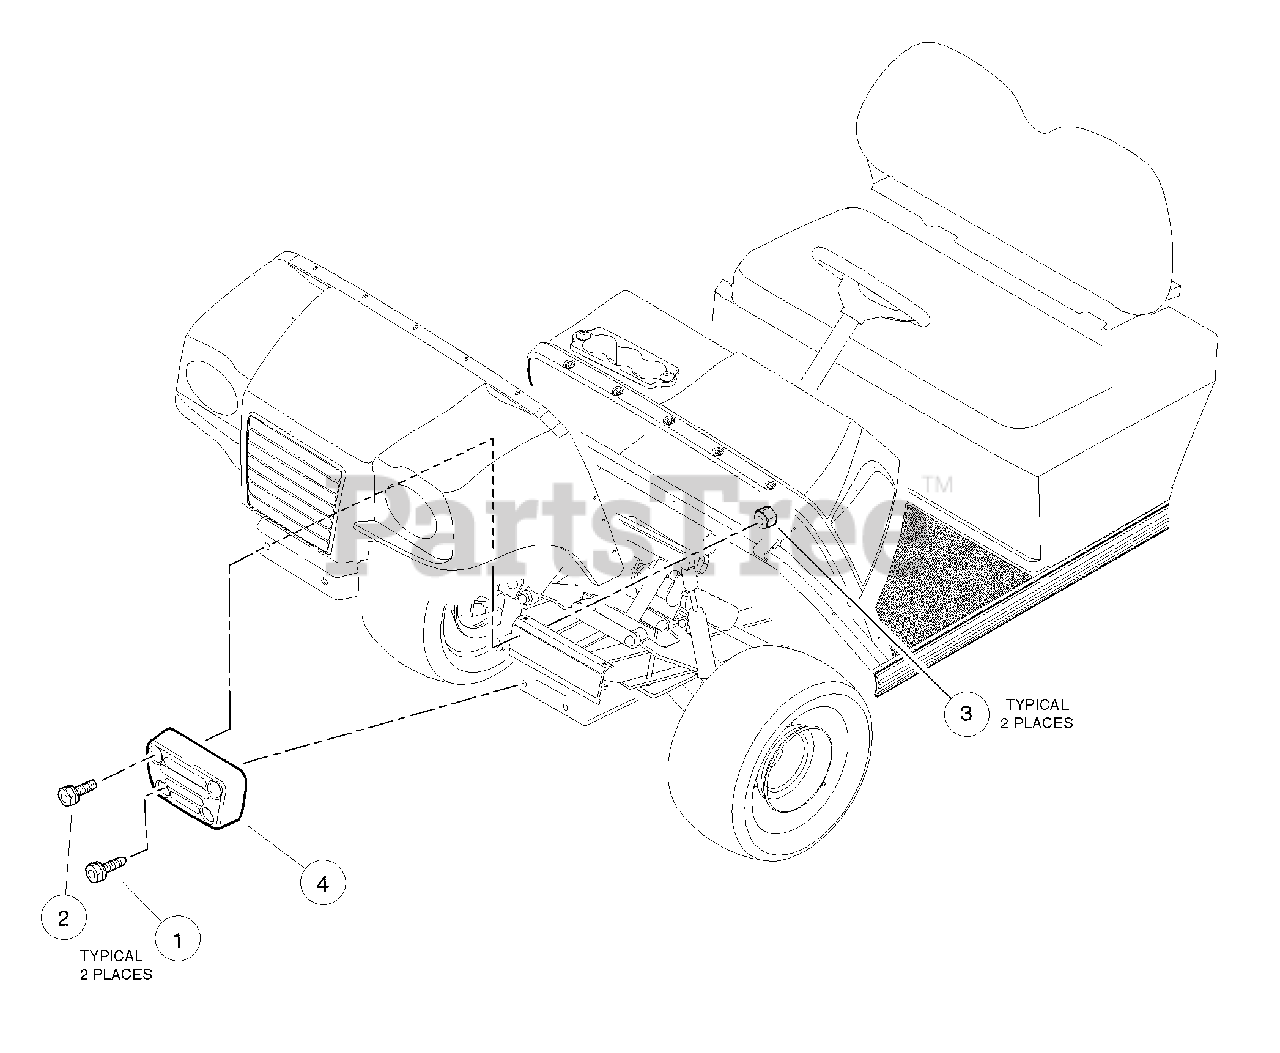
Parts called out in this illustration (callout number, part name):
1	Screw, M8 X 1.25 X 30 Tri, Blk
2	Bolt, Flange Head, M8-1.25 X 40
3	Lock Nut, Flg M8 X 1.25 Nylon
4	Bumper Cast
